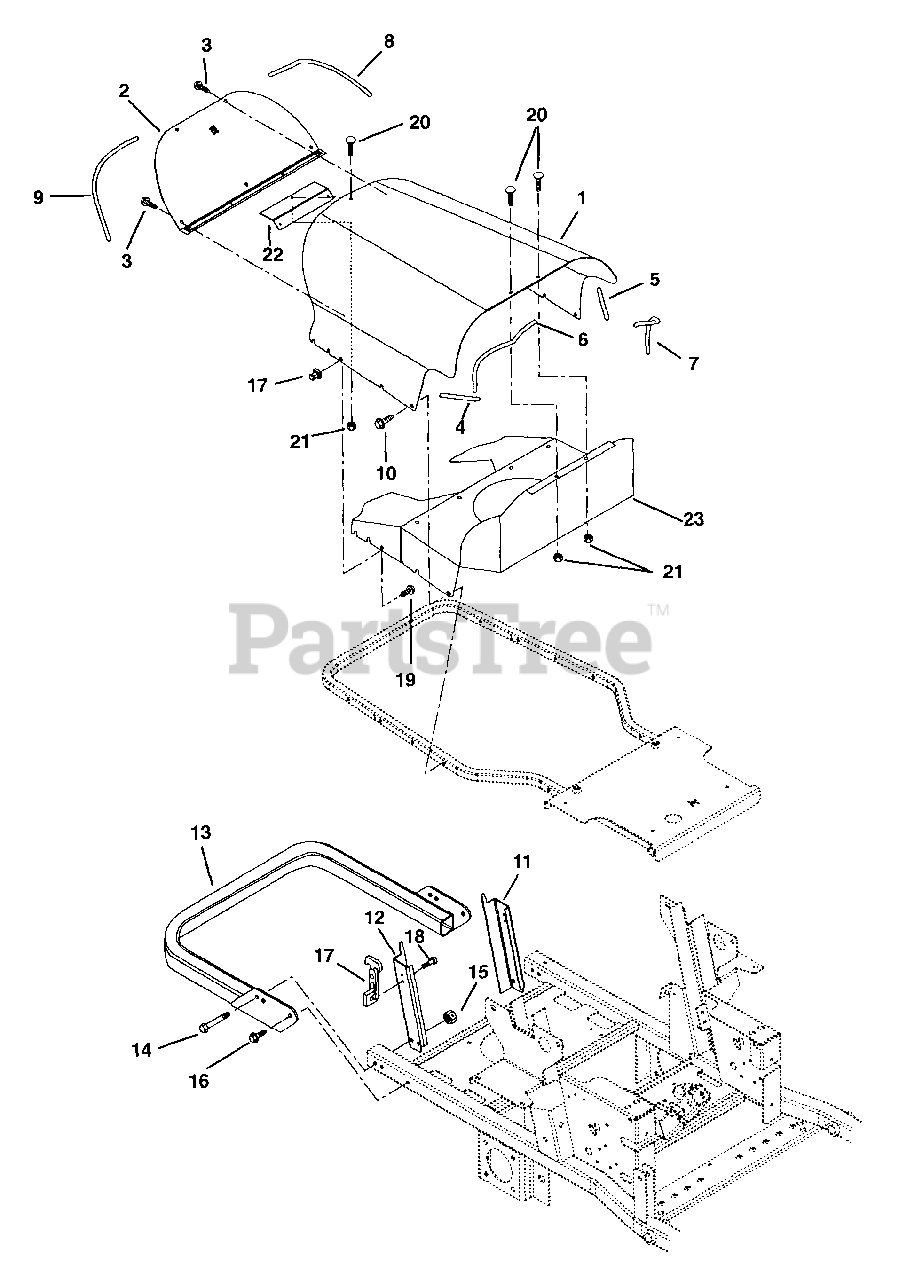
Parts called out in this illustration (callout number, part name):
1	Hood
2	Screen-Hood
3	Screw-Tapping .25-20 x .50 Hex Washer Head
4	Seal-Trim-Lok Bulk .06 Bubble
5	Seal-Trim-Lok Bulk .06 Bubble
6	Seal-Trim-Lok Bulk .06 Bubble
7	Seal-Trim-Lok Bulk .06 Bubble
8	Seal-Trim-Lok Bulk .06 Bubble
9	Seal-Trim-Lok Bulk .06 Bubble
10	Screw-Tapping .38-16 x .50 Hex Washer Head
11	Hood Support Left-Hand
12	Hood Support Right-Hand
13	Bumper-Rear
14	Bolt-Hex .38-16 x 3.00 Grade 5
14	Bolt-Hex .38-16 x 2.50 Grade 5
15	Nut-Locking-Center .38-16
16	Screw-Tapping .38-16 x,75 Hex Washer Head
17	Latch-Rubber
18	Screw-Machine 10-24 x .50 Hex Washer Head
19	Screw Machine 10-24 x .50 Hex Washer Head
20	Bolt-Round Head Square Shank .25-20 x .50 Grade 5
21	Nut-Locking-Nylon .25-20
22	Bracket-Screen Support
23	Weldment, Plenum
